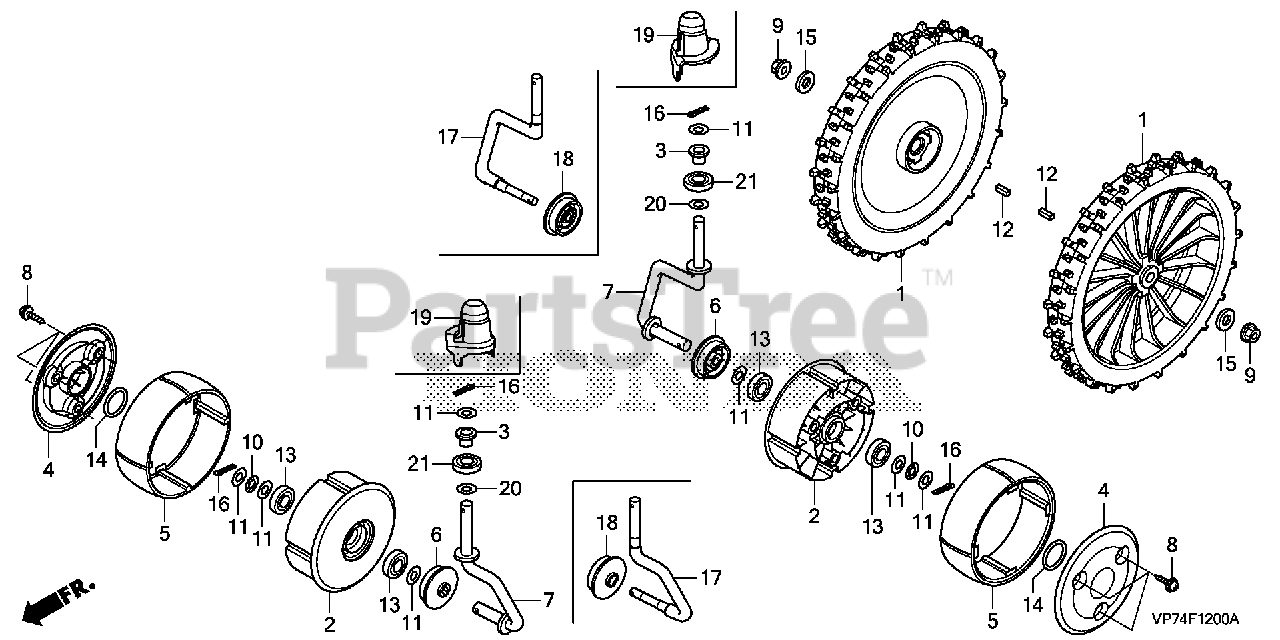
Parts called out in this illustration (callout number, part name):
1	WHEEL COMP, RR.
2	CASTER, FR.
3	BUSH, FR. CASTER
4	COVER, CASTER
5	TIRE, CASTER
8	SCREW, TAPPING (5X16)
9	NUT, SELF-LOCK (6MM)
10	WASHER, WAVE (6MM)
11	WASHER, THRUST (6.2X14X1)
12	KEY FLAT (4X4X14)
13	BEARING (6X17X6)
14	O-RING, FR. CASTER
15	WASHER, PLAIN (6MM)
16	PIN, COTTER (1.6X12)
17	ROD, FR. CASTER
18	CAP, FR. WHEEL
19	CAP, FR. CASTER ROD
21	BEARING (7X17X5)
